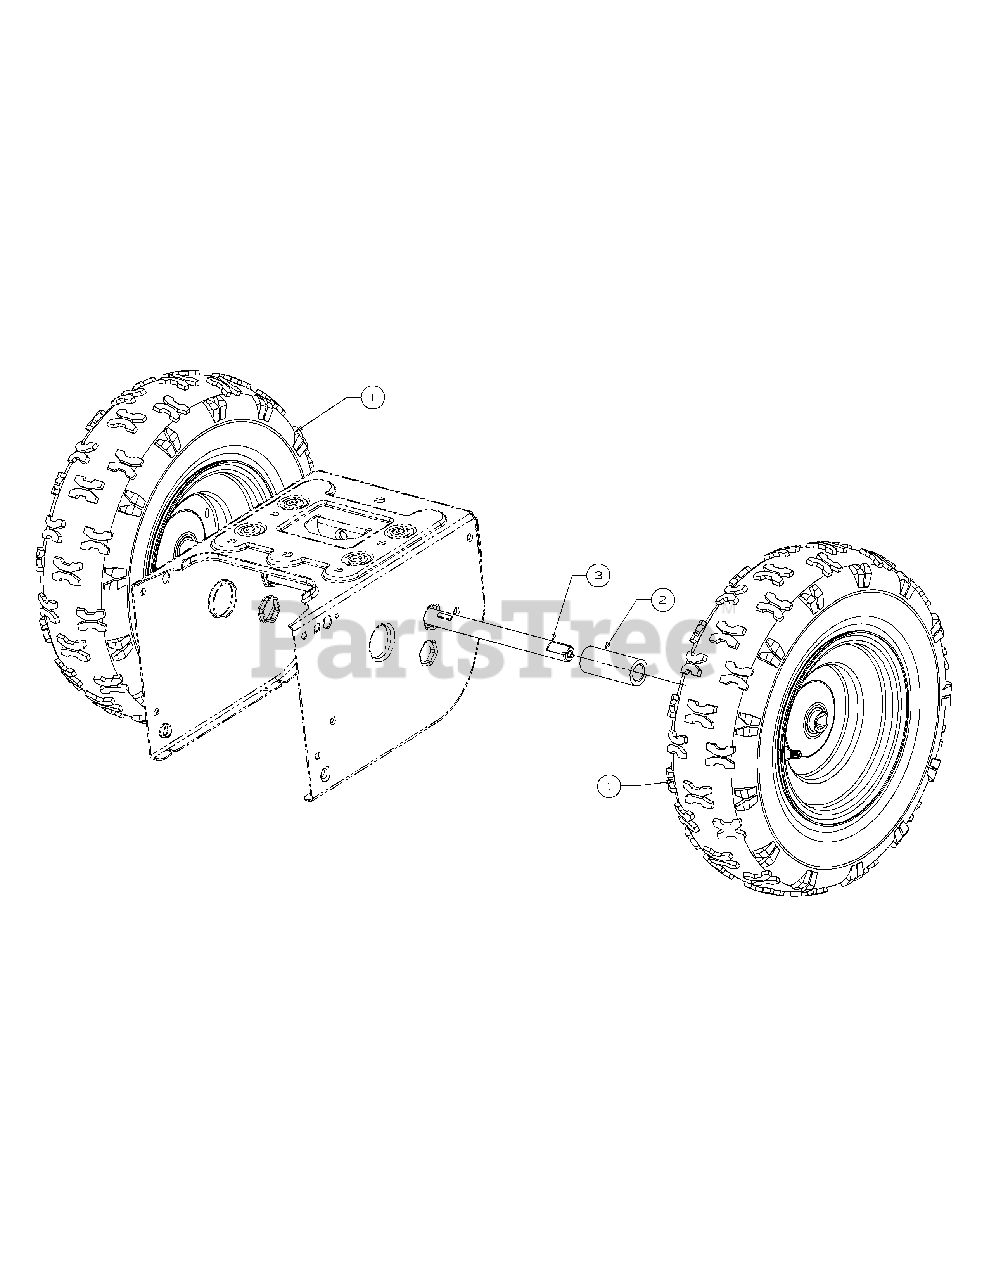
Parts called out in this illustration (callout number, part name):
1	Wheel Asm-Comp 16X4.
2	Spacer-Wheel 1.25O
3	Shaft-Wheel Axle
